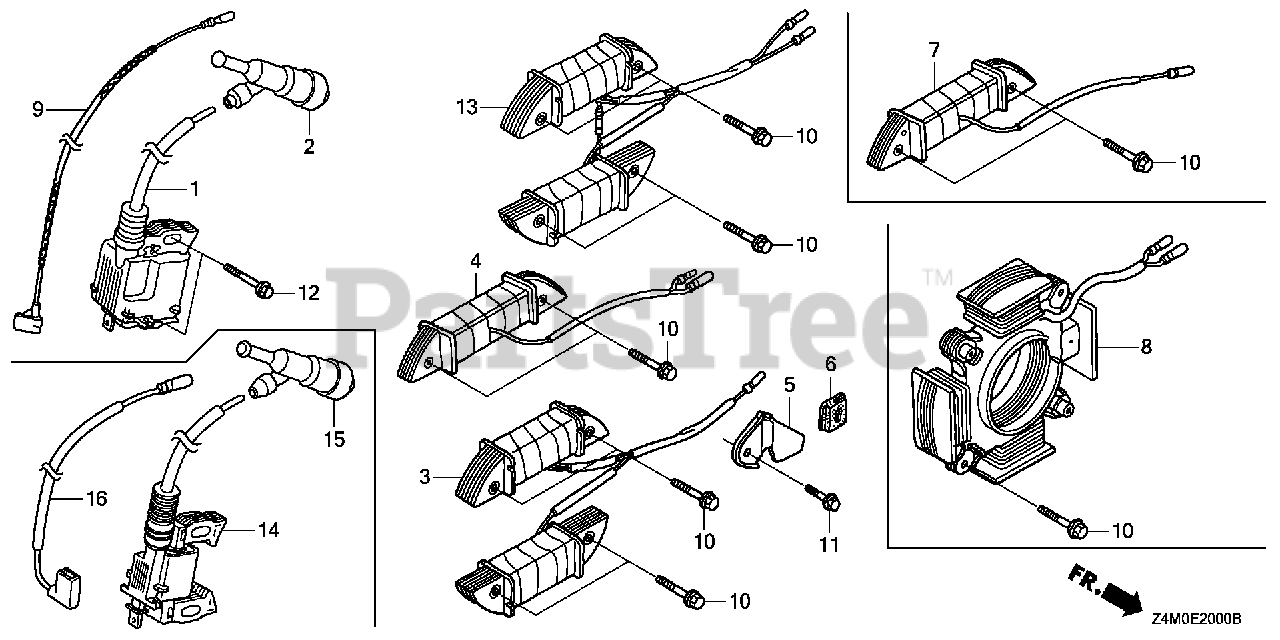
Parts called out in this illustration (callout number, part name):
1	COIL ASSY., IGNITION (TEC)
2	CAP ASSY., NOISE SUPPRESSOR
9	WIRE, STOP SWITCH (370MM)
12	BOLT, FLANGE (6X25) Use up to Engine SN 2056819.
